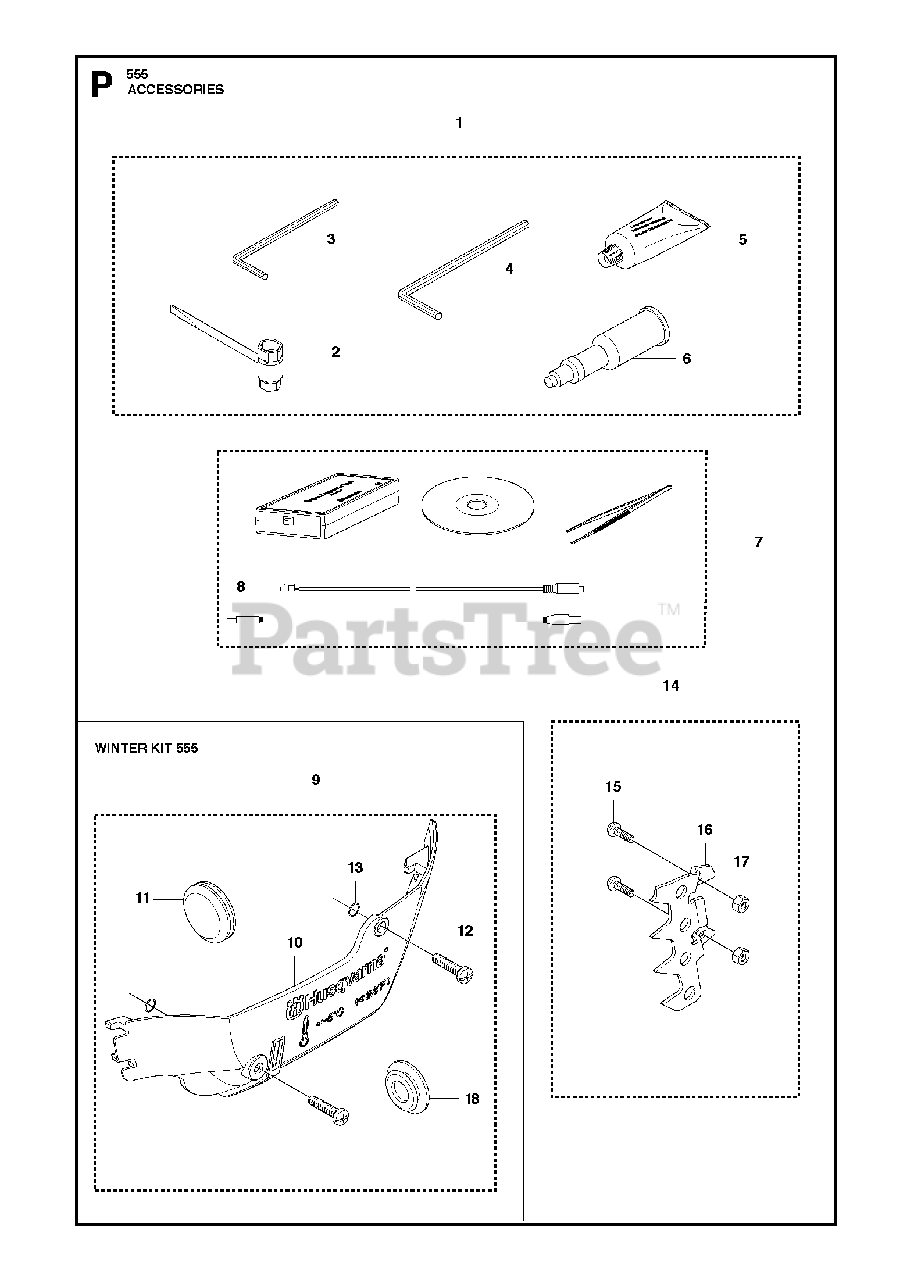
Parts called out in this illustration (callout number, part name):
2	COMBINATION WRENCH
3	L-SPANNER
4	L-SPANNER
5	GREASE
6	Grease Gun
7	SERVICE TOOLS
8	CABLE ASSY
9	WINTER KIT
10	WINTER COVER
11	PLUG
12	SCREW
13	O-RING
14	SPIKE OUTER
15	SCREW
16	SPIKE OUTER
17	NUT
18	RP ENCLOSED KIT
